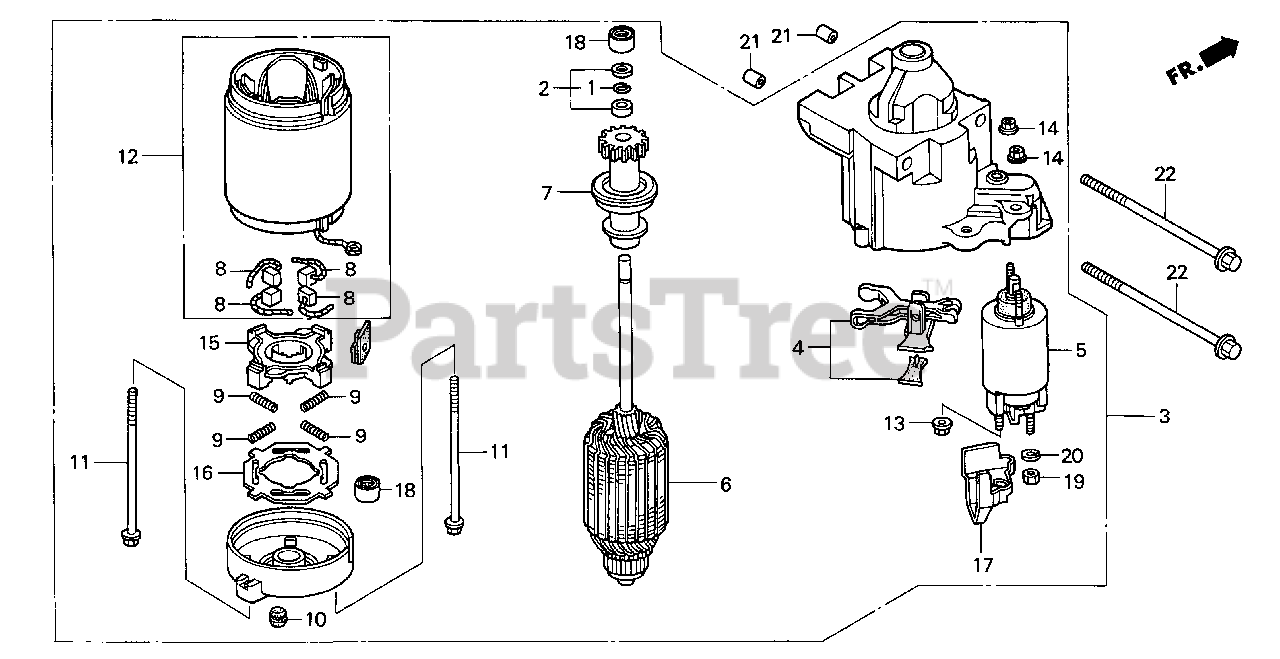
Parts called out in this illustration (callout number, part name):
1	RING, SNAP (DENSO)
2	COLLAR SET, CLUTCH STOP
3	MOTOR ASSY., STARTER
4	LEVER, PINION DRIVE
5	SWITCH ASSY., MAGNET
6	ARMATURE
7	CLUTCH, OVERRUNNING
8	BRUSH
9	SPRING, BRUSH
10	COVER
11	BOLT, THROUGH
12	YOKE
13	NUT, HEX. (8MM)
14	NUT, FLANGE (5MM)
15	HOLDER, BRUSH
16	INSULATOR, BRUSH HOLDER
17	COVER, TERMINAL
18	BEARING A
19	NUT, HEX. (8MM)
20	WASHER, SPRING (8MM)
21	PIN, DOWEL (10X12)
22	BOLT, FLANGE (8X110)
